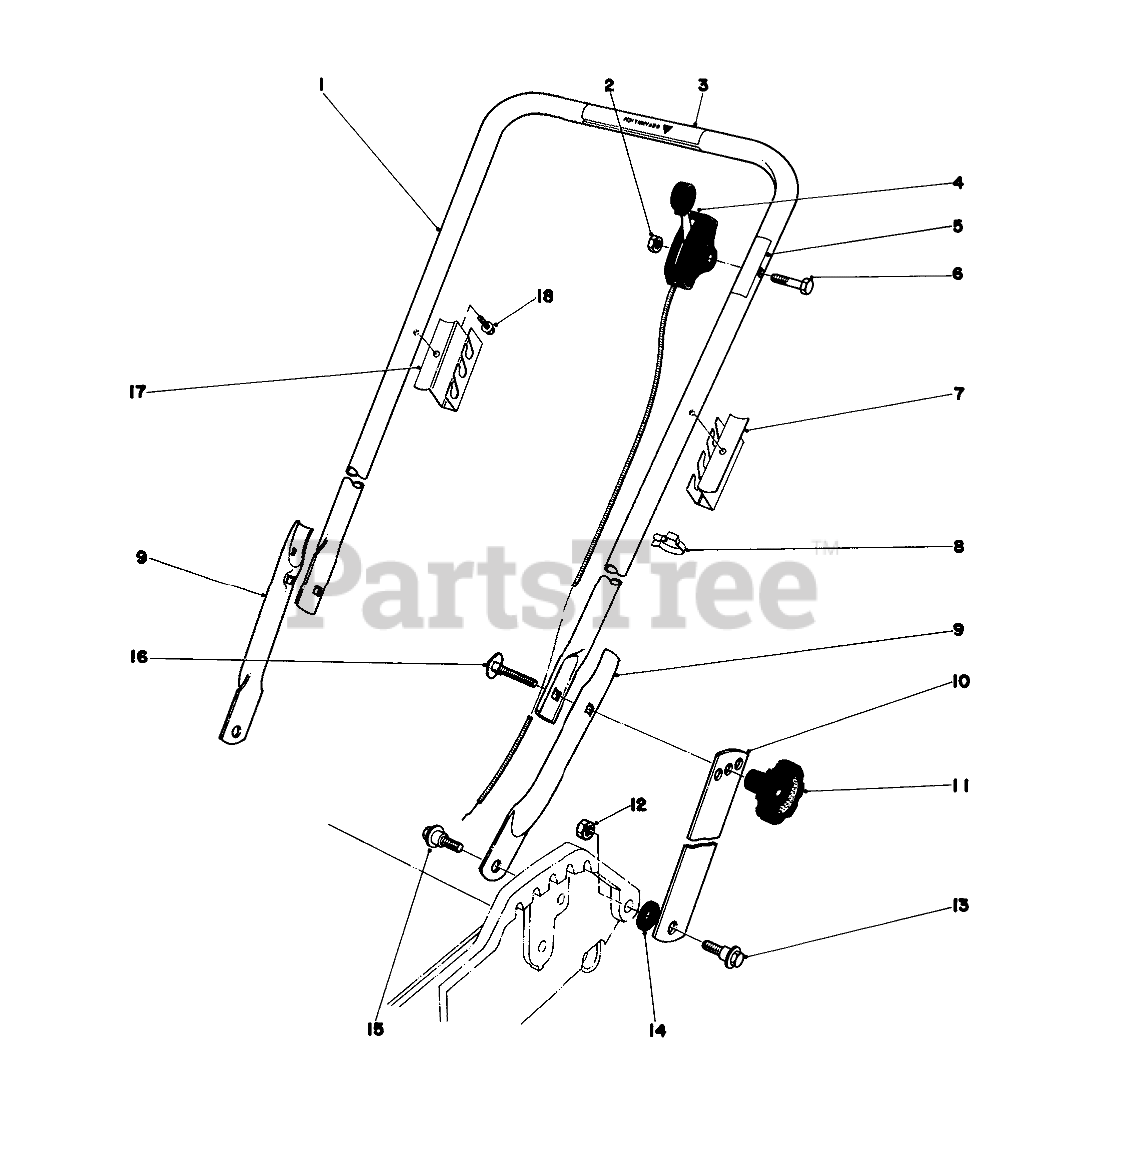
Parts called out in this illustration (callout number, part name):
1	Handle-Upper
2	NUT-LOCK
3	Decal Danger
4	Throttle Control
5	Decal-Throttle
6	SCREW-HH
7	SUPPORT BAG LH
8	BOWDEN CLIP
9	Hand-Lower
10	18" HANDLE LATCH
12	Nut
13	SCREW-SHOULDER
14	SPACER
15	SCREW-SHOULDER
16	SCREW-HANDLE
17	SUPPORT BAG RH
18	SCREW-HWHTF
